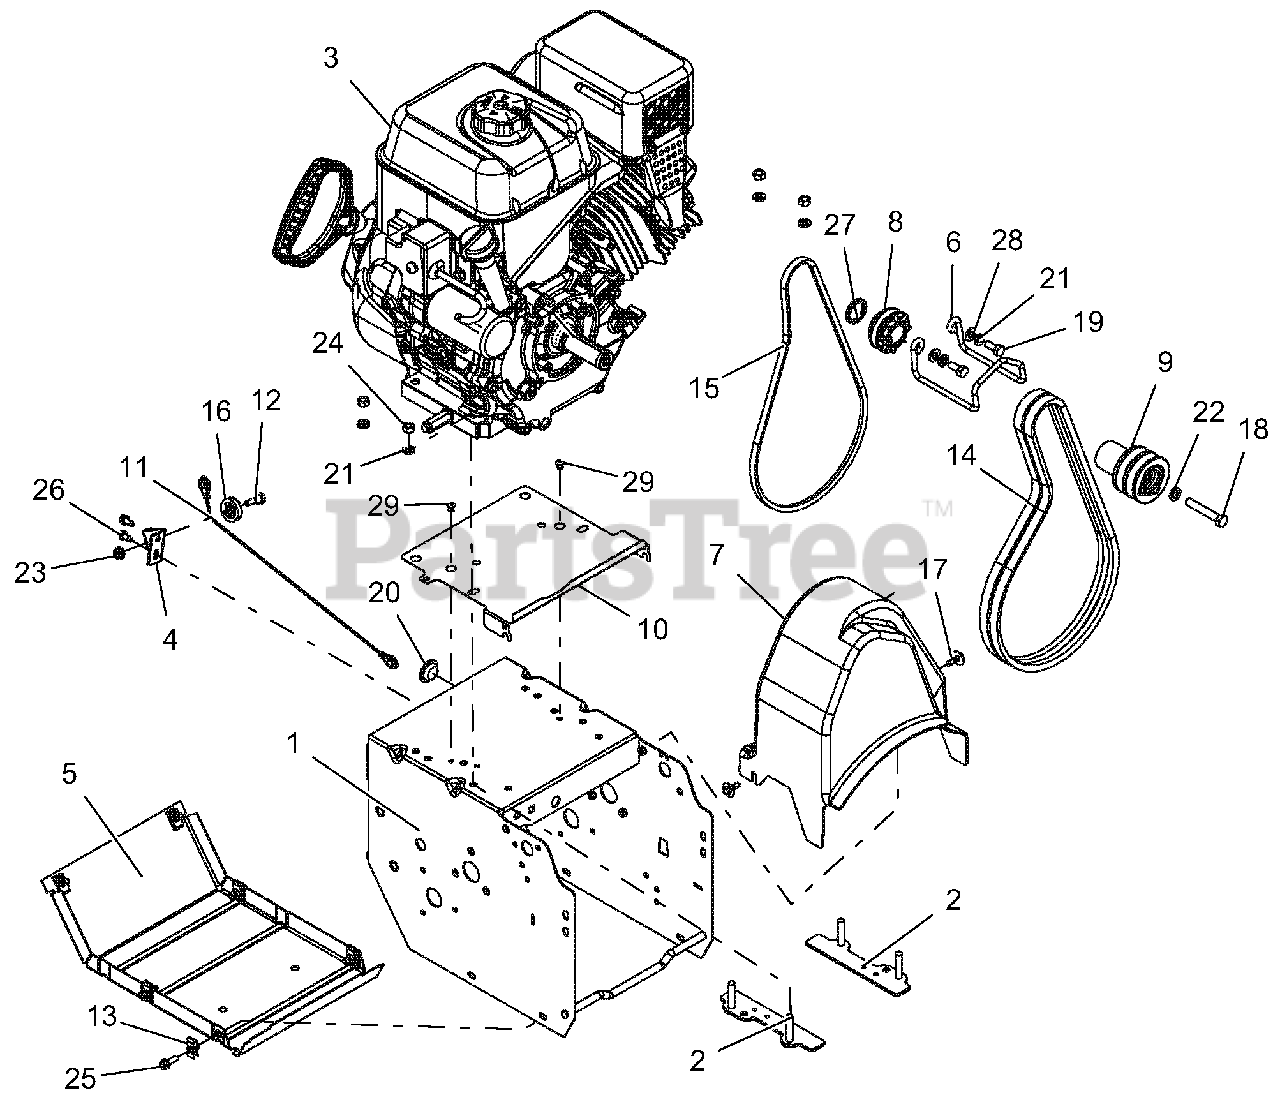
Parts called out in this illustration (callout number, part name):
1	WELDMENT, FRAME - DELUXE 16"
2	STRAP,ENGINE BOLT,ARIENS LRG
3	ENGINE, ARIENS AX414 240V/60W
4	BRACKET, CABLE PULLEY
5	COVER, BOTTOM
6	FINGER, BELT
7	BELT COVER
8	SHEAVE, DRIVE
9	SHEAVE,ATTACHMENT 2-GRV
10	BAFFLE,ENGINE,ARIENS LRG BLOCK
11	CABLE, LOWER TRACTION (DELUXE)
12	BOLT, SHLDR-.375X.375X.25-20
13	NUT-RTNR .25-20X.56
14	V-BELT, HA-RAW EDGE (SET)
15	V-BELT, 3L-RAW EDGE
16	PULLEY, CABLE
17	SCR-TAP .25-20X.5 CAPTIVE
18	BLT-HEX .38-24X2.25 YWZC GR5
19	BLT-HEX .31-24X.75 YWZC GR5
20	PLUG, HOLE - .875" NYLON
21	WSHR-LK .312X.097 HVY YWZC
22	@WSHR-LK .38X.094 REG YWZC
23	@NUT-LK-CTR-FLG .25-20 YWZC
24	@NUT-HEX .31-18 YWZC
25	BLT-HEX .25-20X.75 HWH YZ GR5
26	SCR-TAP .25-20X.50 HWH TR YWZ
27	WSHR-FL-NYL 1.03 X 1.31 X .134
28	@WSHR-FL-STL.344X.688X.065YWZC
29	RVT-POP .187 YZ
